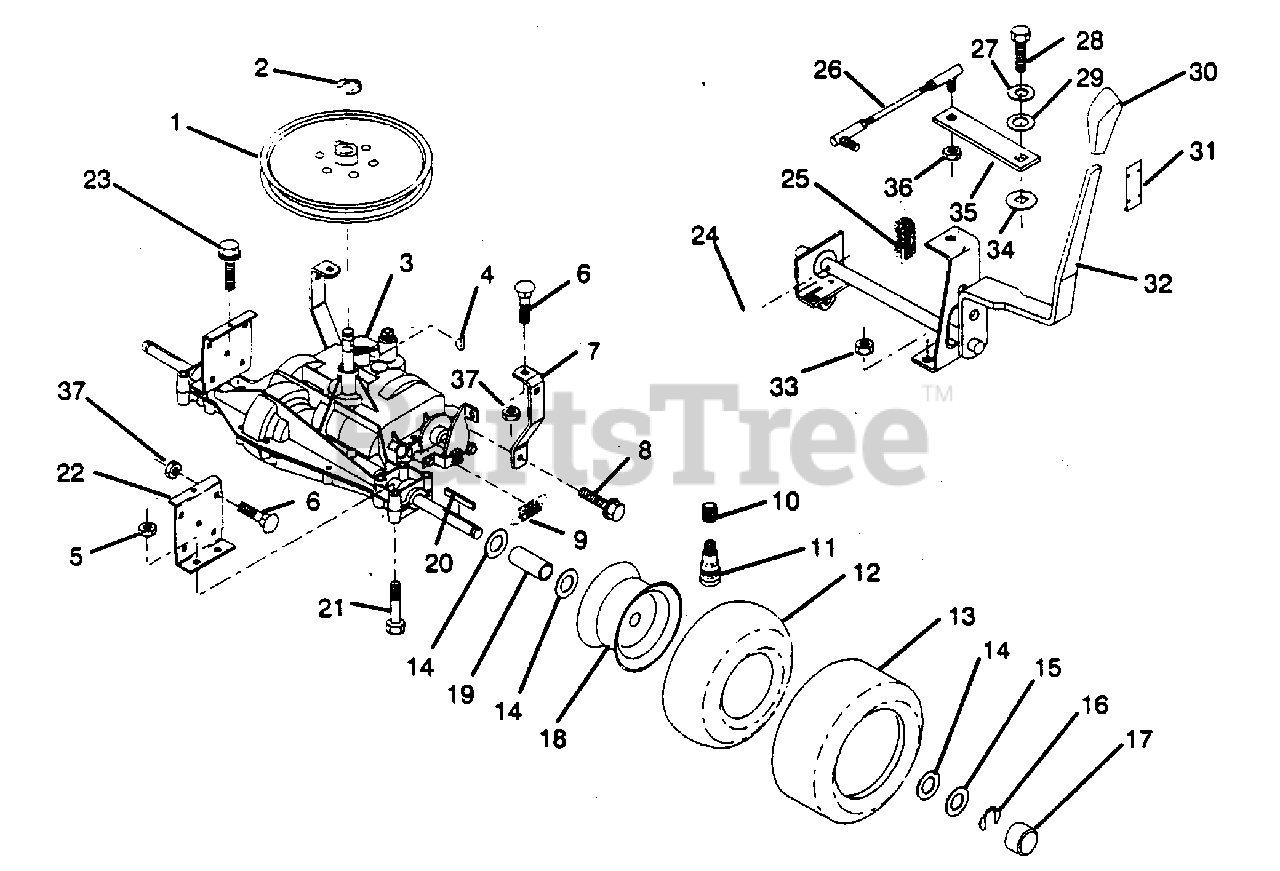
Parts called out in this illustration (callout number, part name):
2	Ring, Retainer
3	Transaxle, Foote 6 Speed, Model No. 4360-18
4	Key, Woodruff #9
5	Nut, Crownlock 3/8-16
6	Bolt, Carriage 5/16-18 UNC x 3/4
7	Strap, Torque
8	Screw, Hex Thdrol. 5/16-18 x 1/2
9	Spring, Brake
13	Tire, Rear
14	Washer 25/32 x 1-1/4 x 16 Ga.
15	Washer 25/32 x 1-5/8 x 16 Ga.
21	Bolt, Fin, Hex 3/8-16x 2-3/4
22	Bracket, Transaxle
23	Screw, 5/16-18 x 3/4
24	Pin, Cotter 1/8 X 1
25	Spring, Extension
27	Washer, Lock Hvy. Helical Spring 1/4
28	Bolt, Fin, Hex 1/4-28 UNF x 3/4 Gr.8
29	Washer 9/32 x 3/4 x 10 Ga.
30	Knob, Shift Contol
31	Retainer, Knob
32	Assembly, Shift Handle
33	Nut, Keps 5/16-18
34	Washer, Shift Plate
36	Nut, Hex Nylon 5/16-24
37	Nut, Crownlock 5/16 - 18
